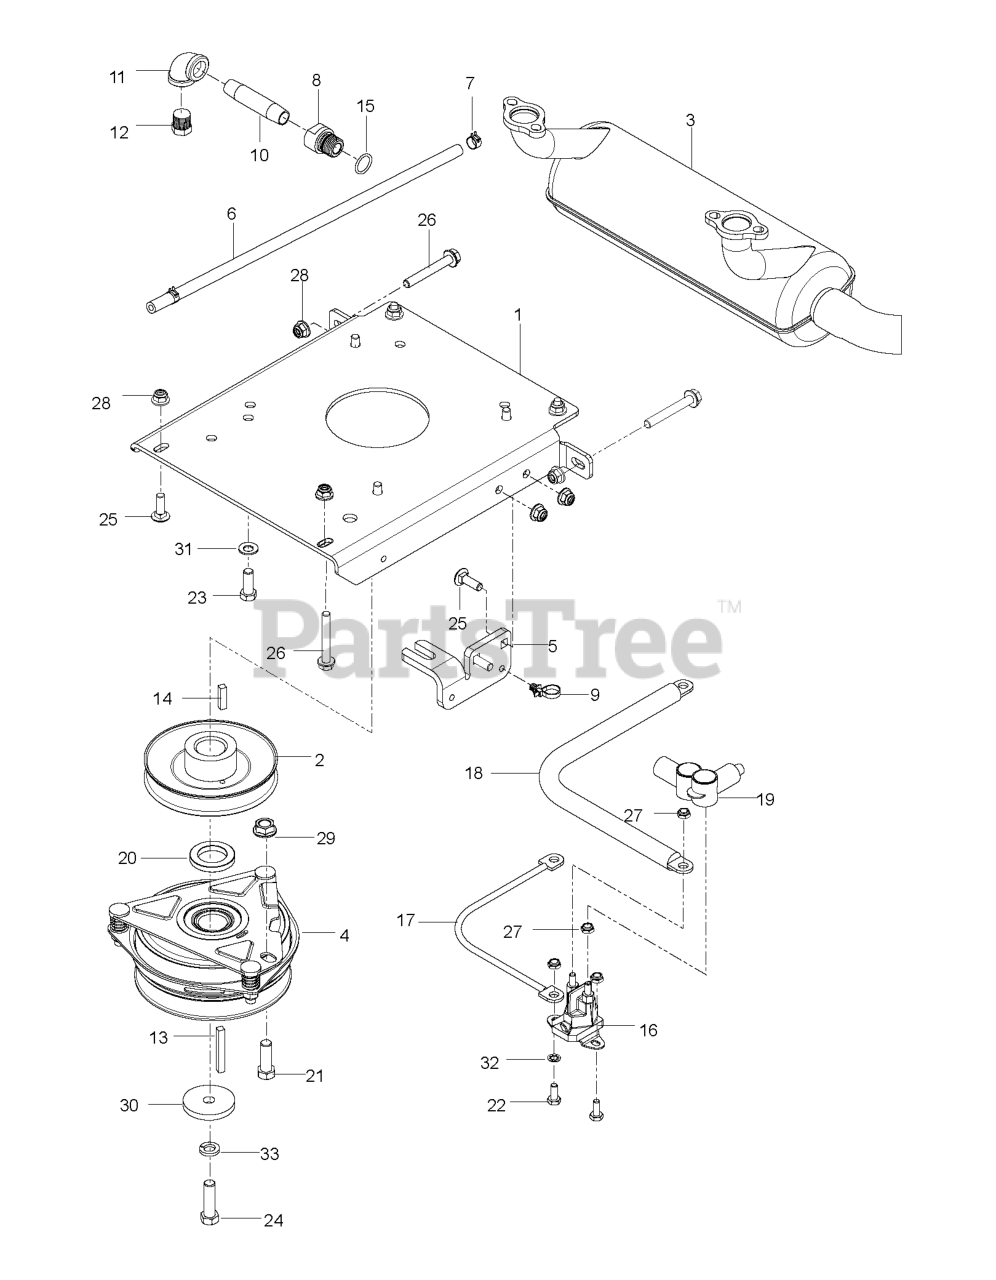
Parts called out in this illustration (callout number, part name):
1	PLATE.ENGINE.BLACK
2	PULLEY, ENGINE
3	MUFFLER.26HP.KAW.FX651V-730V
4	CLUTCH, 150 FT/LBS
5	STOP, CLUTCH, OGURA
6	HOSE 1/4" LOW PERMEATION FUEL
7	HOSE CLAMP
8	ADAPTER, OIL DRAIN
9	TIE WRAP, 8-3/8", W/CLIP
10	PIPE NIPPLE 3/8 X 3
11	90 DEG.ELBOW 3/8NPT
12	PLUG, DRAIN 3/8 NPTF
13	KEY 1/4 SQ X 2
14	KEY 1/4 SQ X 1.0
16	SOLENOID
17	GROUND WIRE (KAW)
18	CABLE POSITIVE
19	INSULATOR
20	SPACER, .25 X 1.135 I.D.
21	HCS 7/16-14 X 1-1/4 GR 5 ZD
22	HCS 1/4C X 5/8
23	HCS 3/8-16X1.GRD.5.ZD
24	CLUTCH BOLT7/16-20X1.5GR5.96HR
25	RHSNB 5/16C X 1
26	HHFS 5/16-18 X 2.25 GD 5
27	JAM NUT 1/4C (2 2 PW01)
28	5/16-18 NYLOC FLANGE NUT
29	NUT 7/16C WHIZ
30	BLADE WASHER
31	WASHER, 3/8 DISC SPRING SPEC
32	WASHER 1/4 INT TOOTH
33	WASHER 7/16 LOCK
